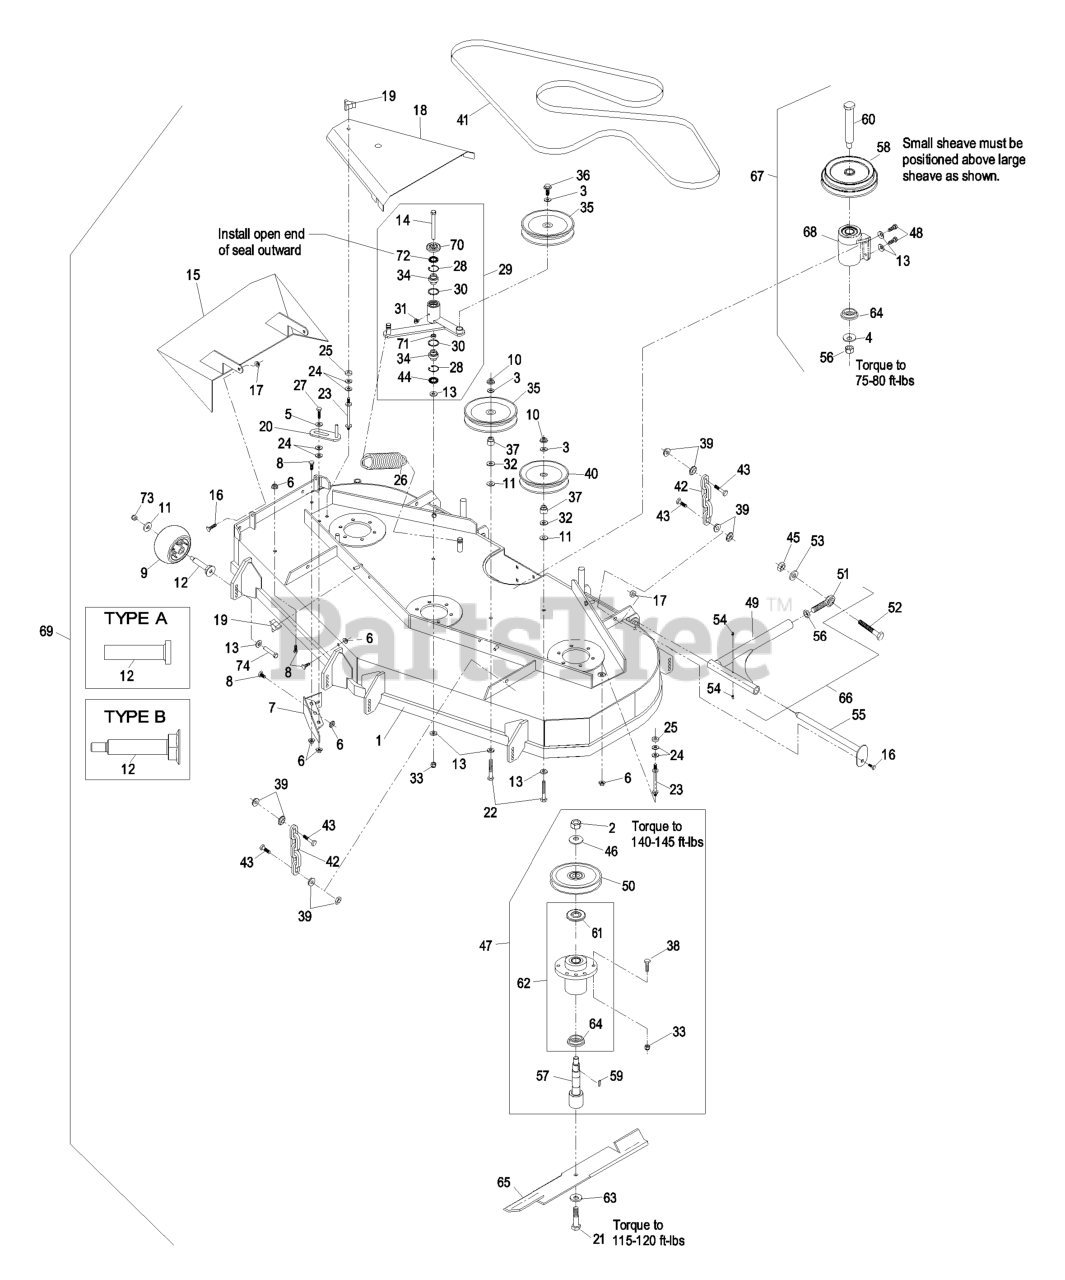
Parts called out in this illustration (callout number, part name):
1	ASM,DECK W/DECALS LZ604
2	NUT-HH
3	WASHER-FLAT
4	WASHER-SPRING
5	WASHER-SPRING
7	WLD,BAFFLE DISCHARGE
8	SCREW-HH
9	ROLLER-SCALP, ANTI
10	NUT-HHF, WHIZ
12	BUSHING-ROLLER
13	WASHER-BELLEVILLE
14	SCREW-HH
15	WLD,CHUTE LZ604
16	SCREW-HH
17	NUT-LOCK, NI
18	SHIELD,BELT
19	KNOB-3 PRONG
20	GUIDE-BELT
21	SCREW-CAP
22	SCREW-HH
23	STUD-SHIELD, BELT (SHORT)
24	WASHER-FLAT
27	SCREW-HH
28	RING-SNAP
29	KIT,DECK IDLER LZ/XP
31	FITTING-GREASE, 90 DEG
32	WASHER-FLAT
33	NUT-LOCK, NI
34	BEARING-SPHERICAL
36	SCREW-HHF
37	BUSHING-IDLER
38	SCREW-HH
40	PULLEY-IDLER
41	BELT,BLADE DRIVE
42	CHAIN-LIFT, DECK
43	SCREW-HH
44	SEAL-LIP, DOUBLE
45	NUT-HEX
47	ASM, CUTTER HSG COMPLETE
48	SCREW-HH
50	SHEAVE,BLADE DRIVE 6.30
51	BALLJOINT-SPHERICAL
52	SCREW-HH
53	WASHER-LOCK
54	FITTING-GREASE
55	PIN-STRUT
56	NUT-HEX
57	SPINDLE,SHORT
58	SHEAVE, JACKSHAFT DOUBLE
60	JACKSHAFT
61	GUARD-BEARING, TOP
62	KIT, CUTTER HOUSING
63	WASHER-BLADE BOLT, HEAVY
64	SPACER-GUARD, BOTTOM
66	STRUT ASM
67	KIT,JACKSHAFT 60/72-3750
69	Complete Deck Assy
70	GUARD-TOP
72	SEAL-LIP, SINGLE
73	NUT-HHF, WHIZ
74	SCREW-HH
